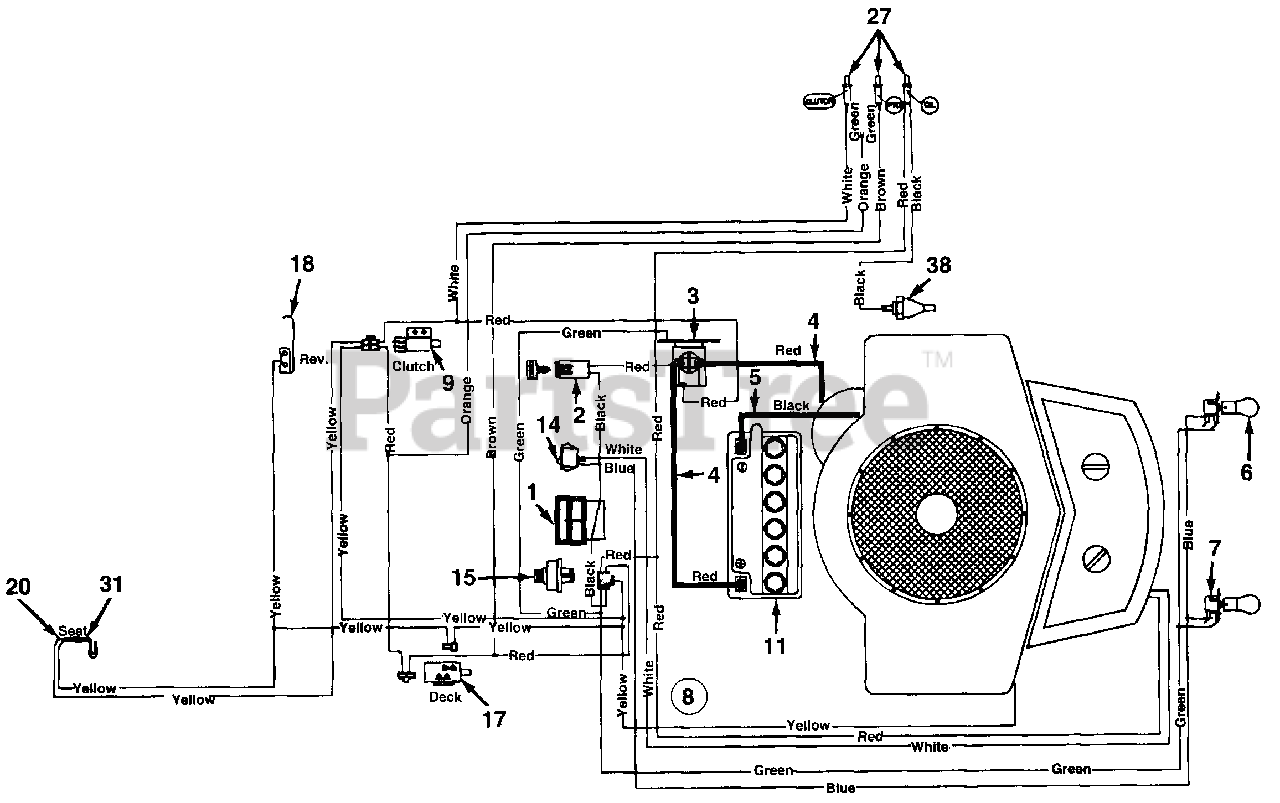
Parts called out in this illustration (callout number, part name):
1	Ammeter
2	Fuse 7.5 Amp
3	Solenoid
4	Wire
5	6 Ga. Black Wire 7.5" Lg.
6	Bulb
7	Socket
8	Wire Harness
9	Safety Switch (Clutch)
11	Battery
14	Light Switch
15	Ignition Switch
17	Safety Switch (Deck)
18	Spring Lever
20	Safety Switch (Seat)
27	Bulb
31	Safety Switch (Seat)
38	Oil Pressure Switch
